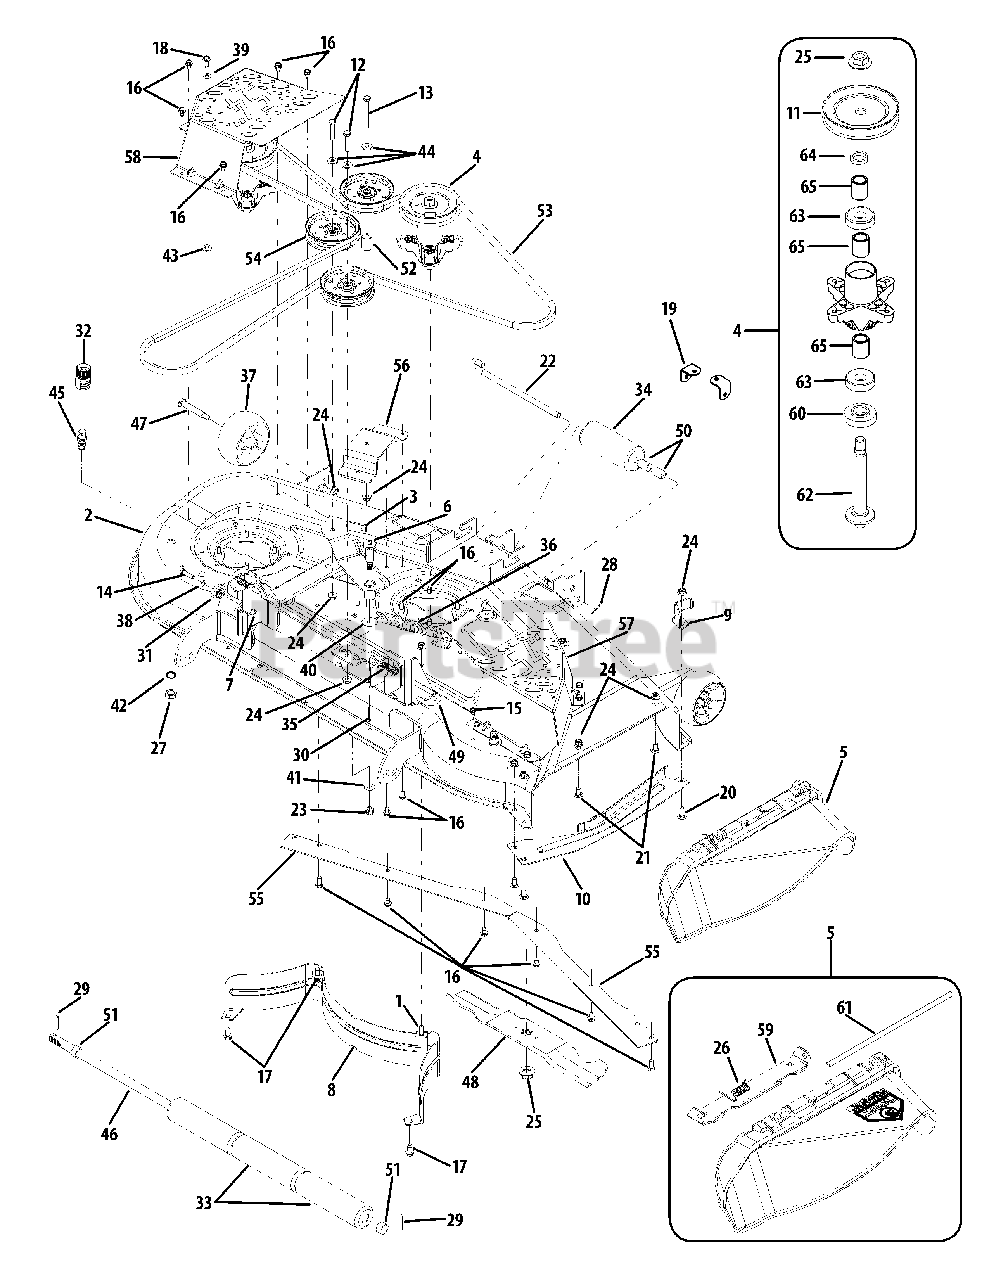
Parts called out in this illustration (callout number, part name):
1	Carriage Screw, 3/8-16 x 1.00
2	Deck Housing
3	Idler Assembly
4	Spindle Assembly
5	Discharge Chute Assembly (Aus.)
6	Shoulder Bolt Assembly
7	Deck Hanger Bracket
8	Rear Inner Baffle
9	Stop Bracket
10	Finger Guard
11	V-Type Pulley, 5.39
12	Hex Cap Screw, 3/8-16 x 1.75
13	Hex Cap Screw, 3/8-16 x 3.0
14	Hex Cap Screw, 5/16-18 x 1.25
15	Hex Washer Screw, 1/4-20 x .5
16	Hex Washer Screw, 5/16-18 x .750
17	Hex Washer Screw, 3/8-16 x .75
18	Hex Washer Screw, 5/16-18 x .875
19	Frame Support Bracket
20	Hex Screw, 3/8-16 x 1.00
21	Carriage Screw, 3/8-16 x .75
22	Roller Pin, .5 x 10.06
23	Hex Lock Nut, 7/16-14
24	Hex Insert Flange Lock Nut, 3/8-16
25	Hex Flange Nut, 5/8-18
26	Torsion Spring, .44 ID x 2.00
27	Hex Nut, M16-1.5
28	Cotter Pin, 3/32 x 1.0
29	Cotter Pin, 5/32 x 1.25
30	Cotter Pin, 1/8 x 1.25
31	Deck Adjustment Gear
32	Water Nozzle Adapter
33	Deck Roller, 7.895
34	Front Roller
35	Compression Spring, .535 x 1.751
36	Extension Spring, .94 x .04609
37	Deck Ball Wheel, 5.0
38	Lock Washer, 5/16
39	Flat Washer, .344 x .688 x .065
40	Flat Washer, .442 x 1.39 x .06
41	Bell Washer, .45 x 1.0 x .062
42	Lock Washer
43	Flat Washer, .407 x .812 x .135
44	Flat Washer, .38 x .93 x .110
45	Deck Wash Nozzle
46	Shaft, .75 x 26.893
47	Shoulder Screw, .5 x 2.5 x 3/8-16
48	Blade, 18.5
49	Deck Hanger Rod
50	Spacer, .55 x .75 x 1.125
51	Spacer, .82 x 1.0 x.53
52	Spacer, .38 x .9 x 1.313
54	Idler Pulley, 4.25 Dia
55	Deck Skirt
56	Stationary Idler Bracket
57	Belt Cover, RH
58	Belt Cover, LH
59	Chute Mounting Bracket
60	Spacer, .79 x 1.82 x .55
61	Hinge Pin
62	Spindle Shaft, 6.95
63	Ball Bearing
64	Spacer, .79 x 1.25 x .175
65	Spacer, .80 x 1.10 x 1.32
